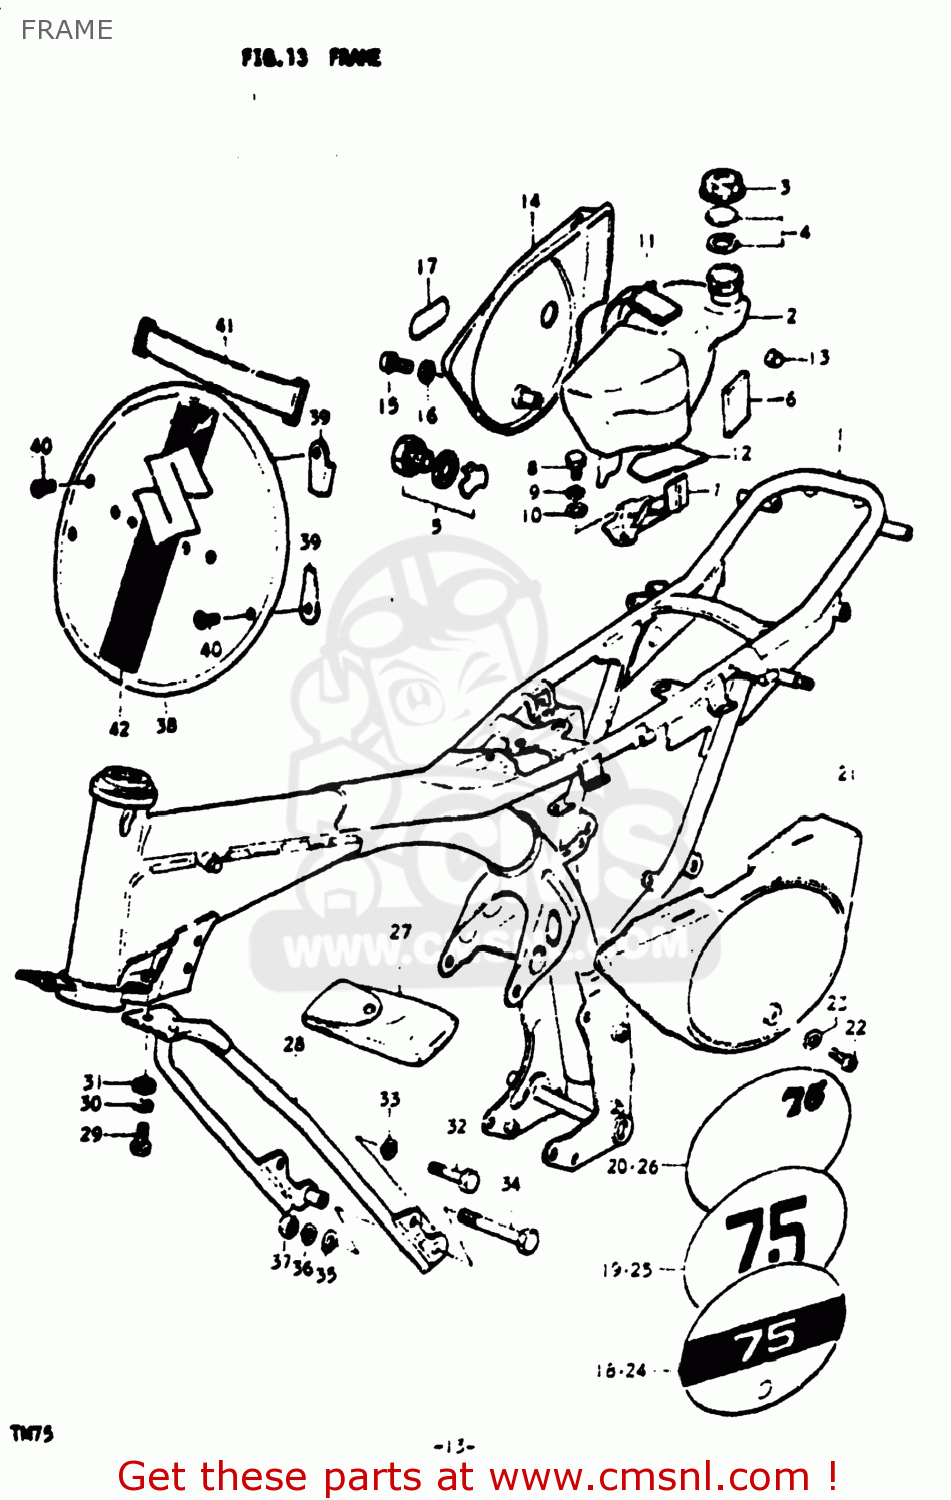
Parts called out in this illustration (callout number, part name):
1	FRAME
2	TANK,OIL
3	CAP,OIL TANK
4	LENS,OIL LEVEL INSPECTION
5	LENS,OIL LEVEL INSPECTION
6	CUSHION 20X45X6
8	BOLT
9	LOCK WASHER
10	WASHER
11	BAND
12	CUSHION
13	CUSHION
14	COVER,FRAME,RIGHT
15	SCREW
16	WASHER
17	EMBLEM,CCIS
18	EMBLEM
19	EMBLEM
20	EMBLEM
21	COVER,FRAME,LEFT
22	SCREW
23	WASHER 5MM
24	EMBLEM,FRAME COVER
25	EMBLEM,FRAME COVER
26	EMBLEM,FRAME COVER
27	TOOL SET
29	BOLT
30	LOCK WASHER
31	WASHER 6MM
32	BOLT
33	LOCK WASHER
34	Bolt 8X50
35	WASHER
36	LOCK WASHER
37	NUT
38	PLATE SET,FRONT
40	SCREW 6X12
41	BAND
42	EMBLEM,FRONT NUMBER PLATE
